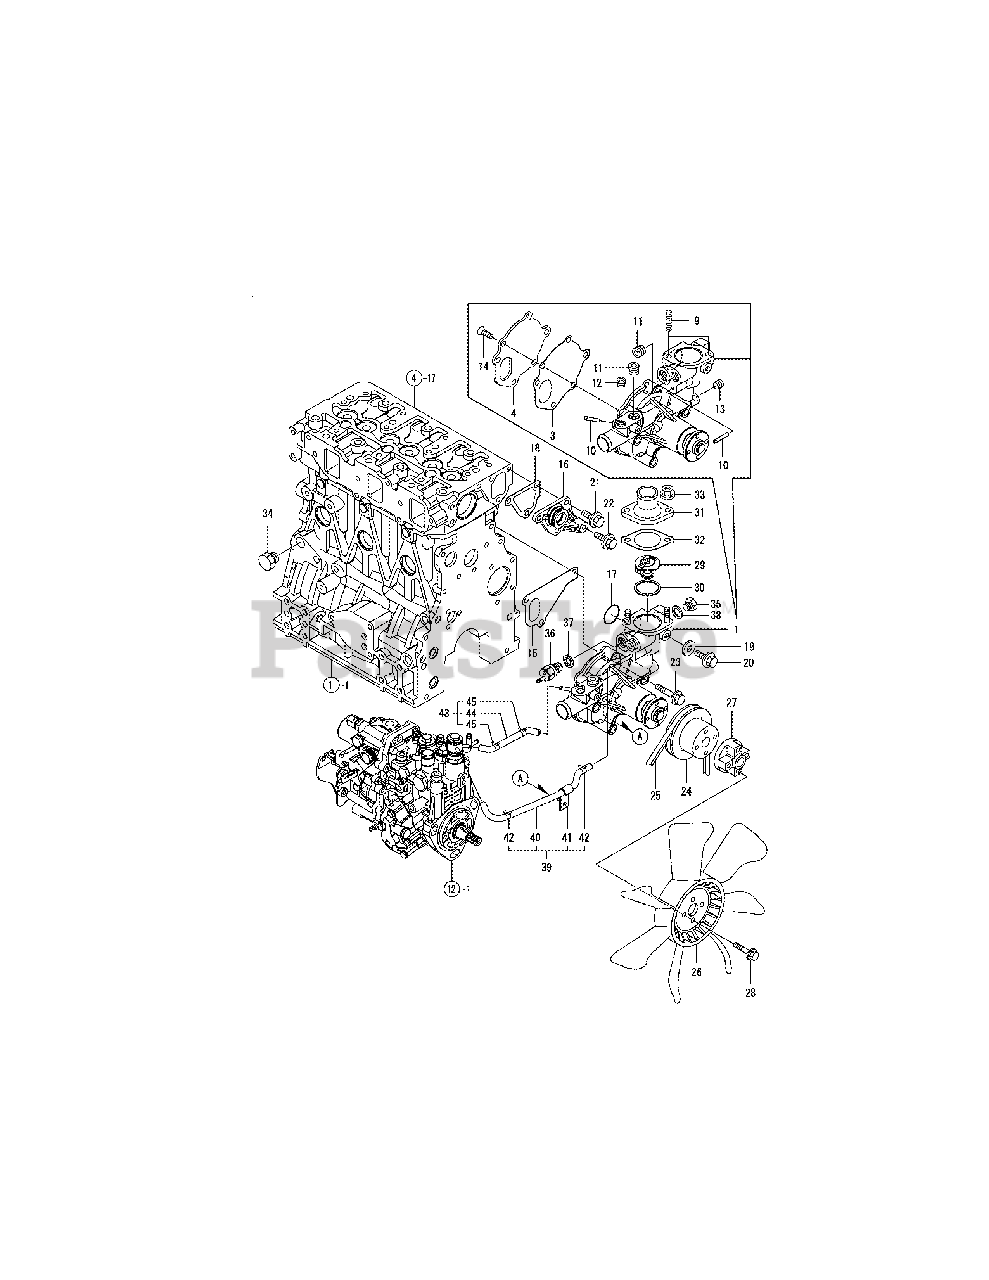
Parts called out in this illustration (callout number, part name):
1	PUMP ASSY, WATER
3	GASKET, (NON-ASB.)
11	PLUG, DRAIN R03
12	PLUG PT1/4,STEEL
13	PLUG PT1/8,SCREW
18	GASKET, THERMO. CASE
19	GASKET 8, ROUND
20	BOLT M 8X 12 PLATED
21	BOLT M 8X 16 PLATED
22	BOLT M 8X 45 PLATED
23	BOLT M 8X 60 PLATED
24	V-PULLEY, F.W.PUMP
28	BOLT M 6X 30 PLATED
30	GASKET, (NON-ASB.)
31	COVER, THERMOSTAT
32	GASKET, (NON-ASB.)
36	SWITCH, THERMO(110
39	PIPE ASSY, A MP2
40	PIPE ASSY, A MP2
43	PIPE ASSY, B MP2
44	PIPE, WATER B MP2
